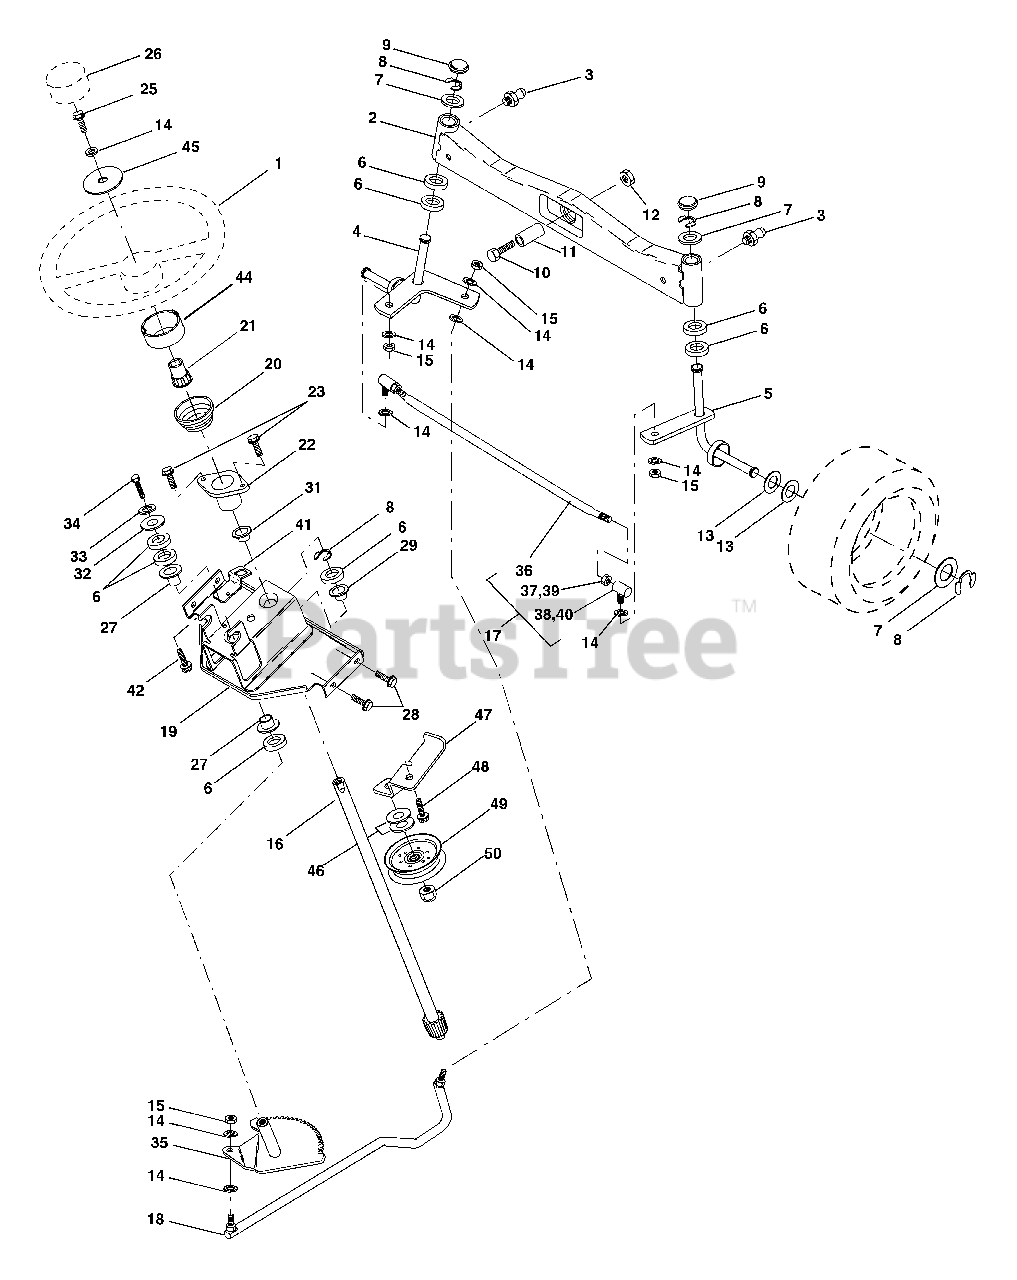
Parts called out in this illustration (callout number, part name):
1	Wheel, Steering
2	Axle Asm., Front
3	Fitting, Grease
4	Spindle Asm, LH
5	Spindle Asm., RH
6	Bearing, Race Thrust Harden
7	Washer 25/32 x 1-5/8 x 16 Ga.
8	Ring, Klip #T5304-75
9	Cap, Spindle
10	Bolt, Fin Hex 5/8-11 x 2-3/4
11	Spacer Brg Axle Front 1.570
12	Nut, Lock Flange 5/8-11 Unc
13	Washer 25/32 x 1-1/4 x 16 Ga.
14	Washer, Lock Hvy Hlcl Spr 3/8
15	Nut Lock Center 3/8-24 Unf
16	Shaft Asm., Steering
17	Rod Asm., Tie Ball J Ball Vgt
18	Draglink, Ball Joint Solid Vgt
19	Support Asm., Steering Vgt
20	Boot Steering
21	Adapter, Wheel Steering
22	Bushing, Strg.
25	Bolt, Fin Hex 3/8-16 x 1 Gr. 5
26	Cap , Wheel Steering
27	Bearing, Col. Strg.
28	Screw 3/8-16 x 3/4
29	Bearing, Flange
31	Bushing, Nyliner Snap
32	Washer 11/32 x 1 x 10 Ga.
33	Washer, Lock Hvy Hlcl Spr 5/16
34	Bolt, Hex Hd 5/16-18 x 3/4
35	Gear, Sector Steering
36	Tie Rod
37	Jam Nut RH Thread
38	Joint Asm. Ball RH Thread
39	Nut Hex Jam 3/8-24 UNF LH
40	Joint Asm Ball LH
41	Bracket Switch Inerlock VGT97
42	Screw 5/16-18 x 1/2
44	Extension Steering Premium
45	Washer 13/32 x 1-1/20 x 11 Ga.
46	Washer FLat 13/32 x 1/10 Ga.
47	Bracket Asm. Idler
48	Screw 3/8-16 x .75
49	Pulley Idler Flat
50	Nut Lock Flg 3/8-16 Unc
